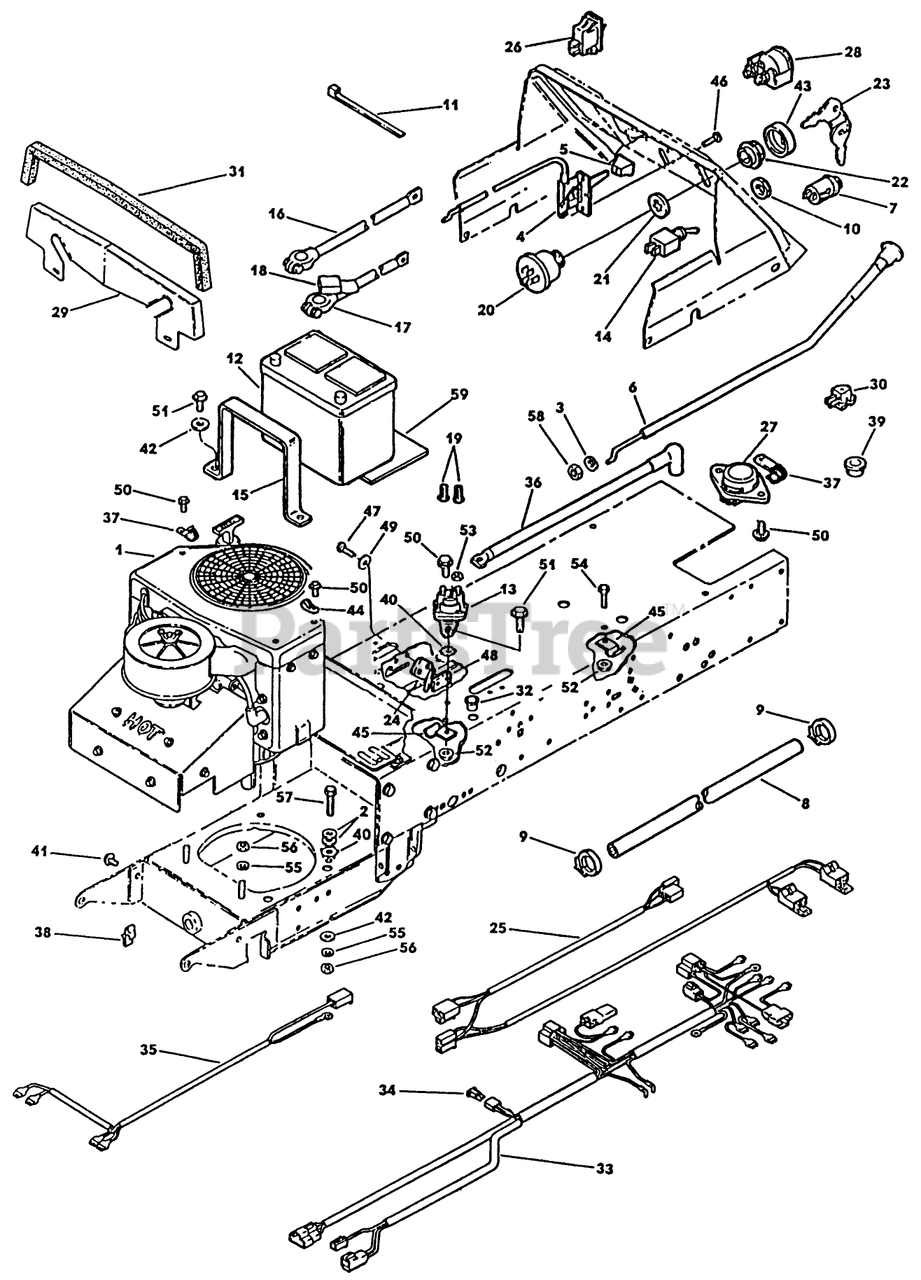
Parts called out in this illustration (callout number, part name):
1	Engine-Kohler 16 H.P.
3	WASHER
4	THROTTLE CONTROL
5	THROTTLE KNOB
7	LIGHT-PTO INDICTOR
13	SOLENOID
14	SWITCH-PTO W/SAFTY
15	STRAP & DECAL AY.
22	NUT
23	KEY
24	SWITCH-SEALED
26	SWITCH ASSEMBLY
27	SWITCH,SEAT
29	DAM - AIR
30	SWITCH
38	CLIP
43	BEZEL
53	NUT-HEX
54	SCREW-HH
56	NUT SS
58	NUT-HEX
